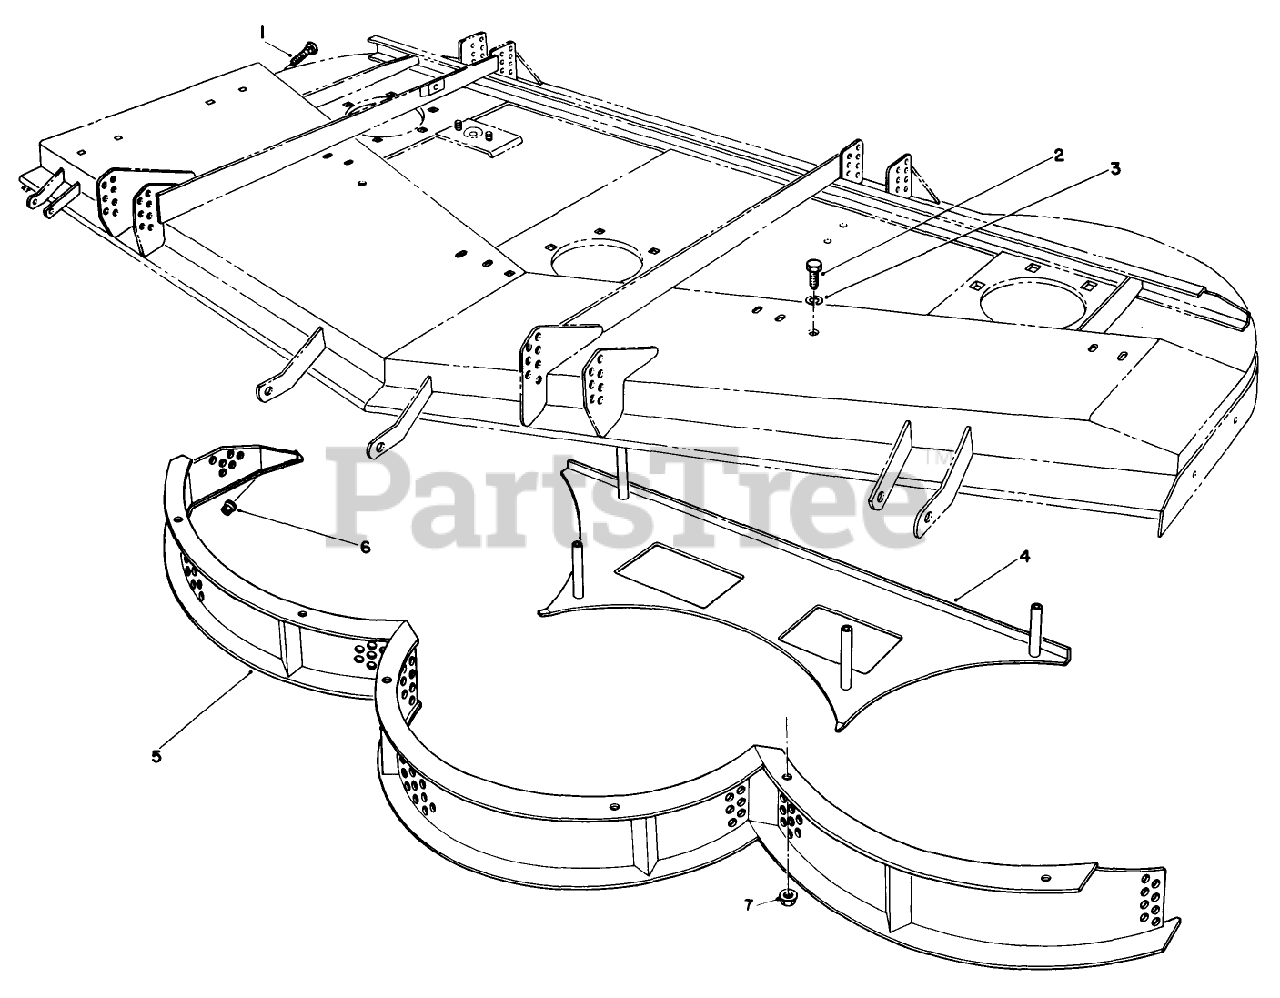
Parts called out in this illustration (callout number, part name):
1	BOLT-CARR
2	SCREW-HH
3	WASHER-LOCK
4	Shelf
5	Screen W.A.
6	NUT-HF
7	NUT-HHF, WHIZ
